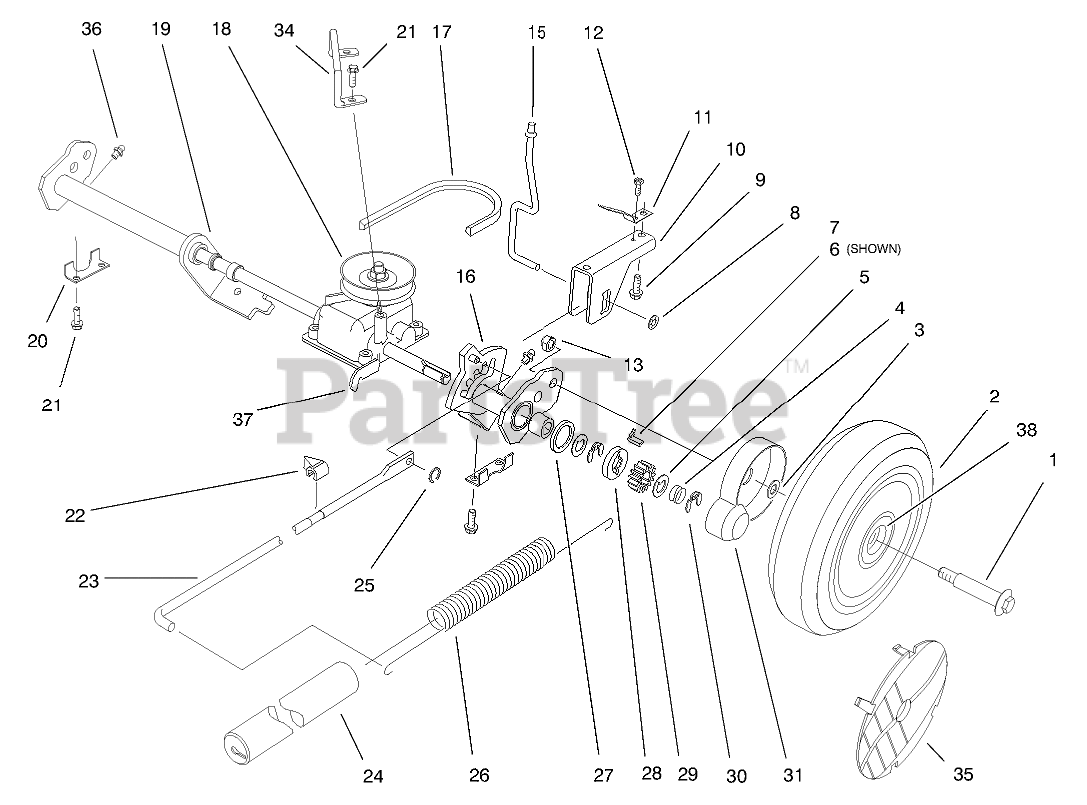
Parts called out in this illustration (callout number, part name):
1	BOLT-WHEEL
2	WHL & TIRE ASSEMBLY
3	SPACER-COVER, WHEEL
4	SPRING-COMPRESSION
5	WASHER-THRUST, KEYED
6	KEY-ROCKING, LH
7	KEY-ROCKING, RH
8	PUSHNUT
9	SCREW
10	SADDLE - HOC
11	SPRING - TRIGGER RET
12	SCREW 8 - 32 X 250
13	NUT-HEX
15	TRIGGER ROD
16	ASM - LH PIVOT ARM
17	V-BELT
18	GEAR CASE ASSY
19	ASM - RH PIVOT ARM
20	REAR SECURING PLATE
21	SCREW-HWH
22	INDICATOR-HEIGHT OF CUT
23	LINK ROD
24	COVER-SPRING
25	GRIP RING
26	SPRING-COUNTERBALANCE
27	RING-FRICTION
28	WASHER-CLUTCH
29	GEAR-PINION
30	RING-CLIP, LOCKING
31	COVER-WHEEL
34	Retainer Belt
35	COVER-WHEEL
36	FITTING-GREASE
37	Bracket-Traction
38	BUSHING
